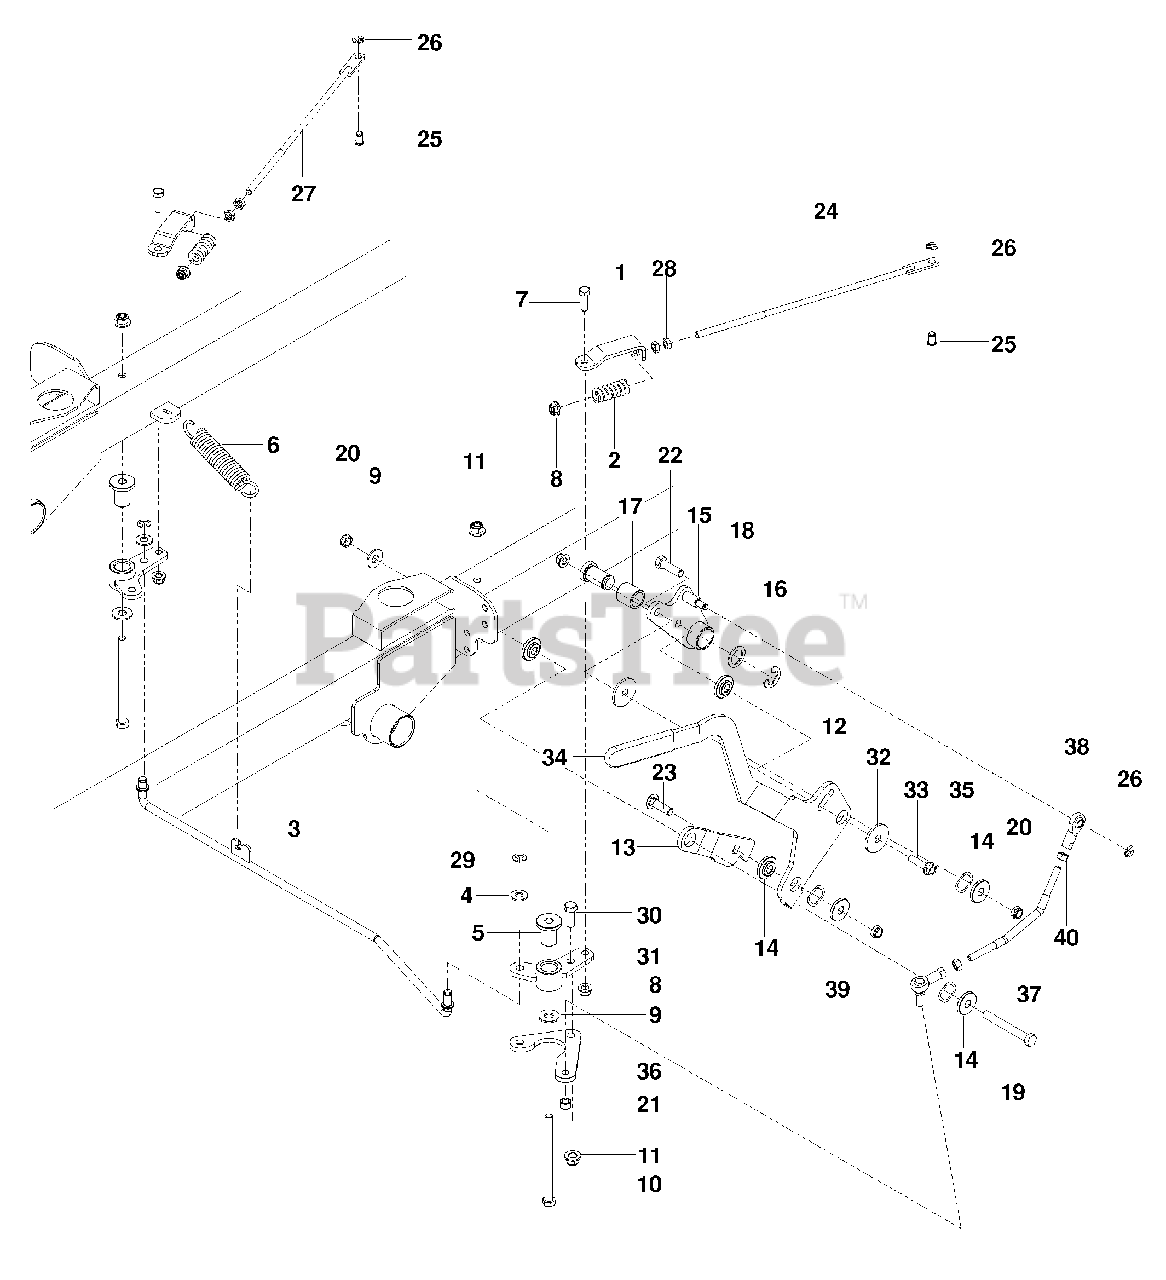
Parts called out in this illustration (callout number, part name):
1	Bracket, Brake
3	Linkage, Brake, Primary
4	Washer 3/8 Sae Flt
5	Bushing, Pivot
7	Hcs 5/16-18 X 1
8	Nut 5/16-18 Hex Flange Nyloc
9	Washer 3/8 Flt Std
10	Hcs 3/8-16 X 5
11	Nut 3/8-16 Hex Flg Nyloc
12	Lever, Brake Blk
13	Link, Follower
14	Bushing, Brake
15	Arm, Brake
16	E-Ring 3/4"
17	Bushing 3/4 X 1 Sleeve
19	Hcs 3/8-16 X 3
20	Nut 3/8-16 Hex Jam Nyloc
21	Nut 5/16-24 Nyloc
22	Hcs 3/8-16 X 1 1/4
23	Rhsnb 3/8-16 X 1 1/4
24	Linkage, Brake Lt-Rr
25	Pin, Brake Arm
26	Ring 5/16 Retaining Ext
27	Linkage, Brake, Rt-Rr
28	Nut 5/16-18 Hex Jam
29	E- Ring 3/8"
30	Hcs 3/8-16 X 1
31	Bellcrank, Brake
32	Washer 1/8 Friction
33	Hhfs 5/16-18 X 1 1/2 Tpblt
34	Grip, Lever
35	Washer, Wave
36	SCREW 3/8-16 x 1 1/2 HEX HD
37	Linkage, Brake
38	Ball End, Rh
39	Rod End, Spherical Rh
40	Nut 5/16-24 Hex
